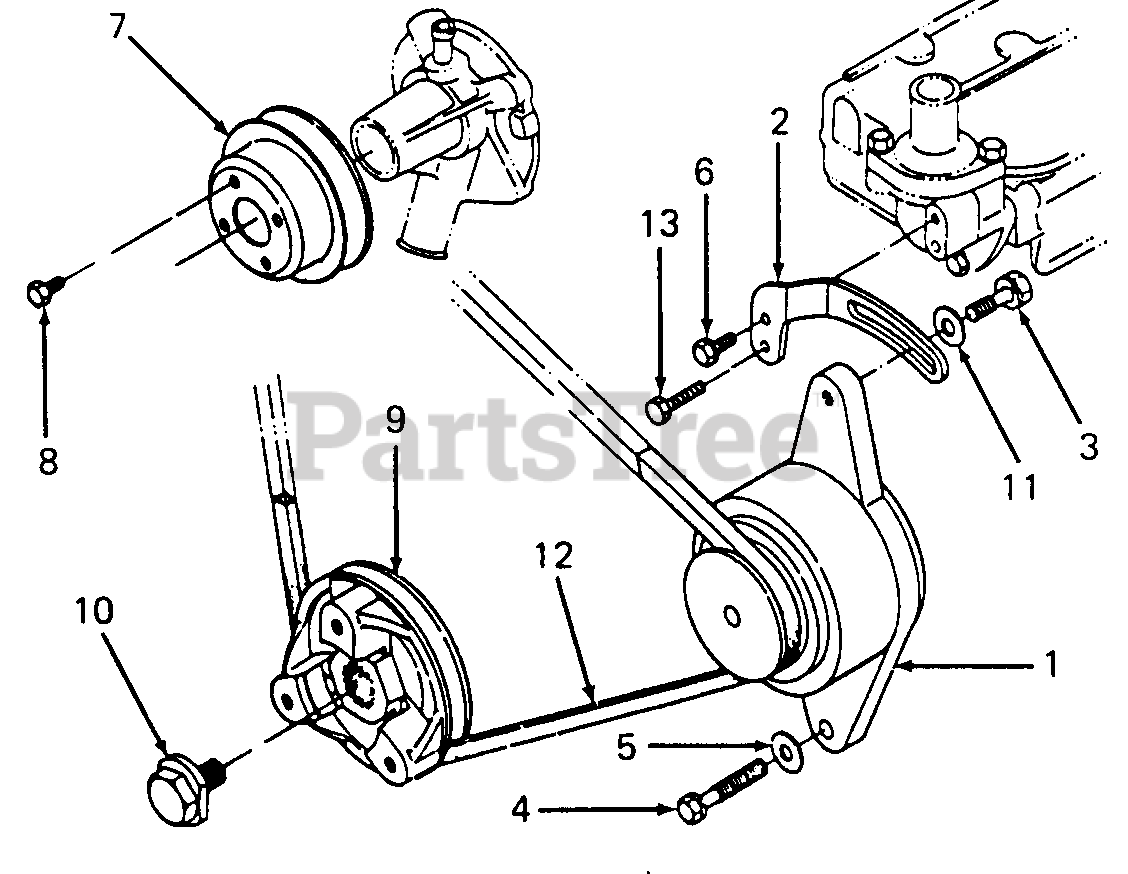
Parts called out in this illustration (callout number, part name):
1	Alternator
2	Support, Alternator
3	Screw w/Washer
4	Screw w/Washer
6	Screw w/Washer
7	Pulley, Water Pump
8	Screw, Hex Washer Head
9	Pulley, Alternator Drive
13	Screw w/Washer
